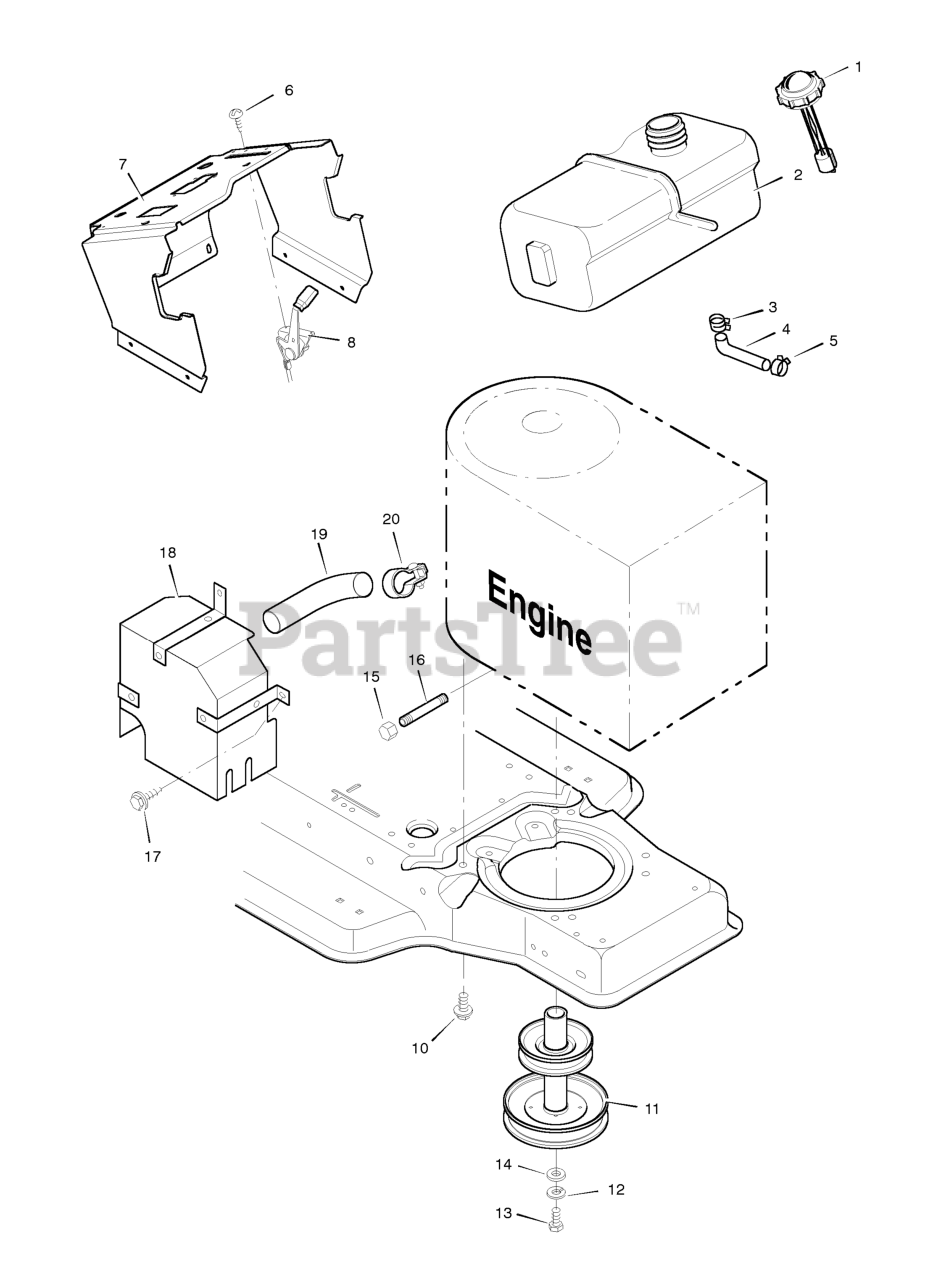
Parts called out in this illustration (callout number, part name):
1	Fuel Cap
2	Fuel Tank
3	Hose Clamp
4	Fuel Line
5	Hose Clamp
7	Support, Dash
8	Throttle Control
9	Engine *
10	Bolt, Engine Mount
11	Stack Pulley Assembly
12	Lockwasher
13	Bolt, Hex
15	Cap, Oil Drain
16	Pipe, Oil Drain
18	Shield, Heat
19	Pipe, Exhaust
